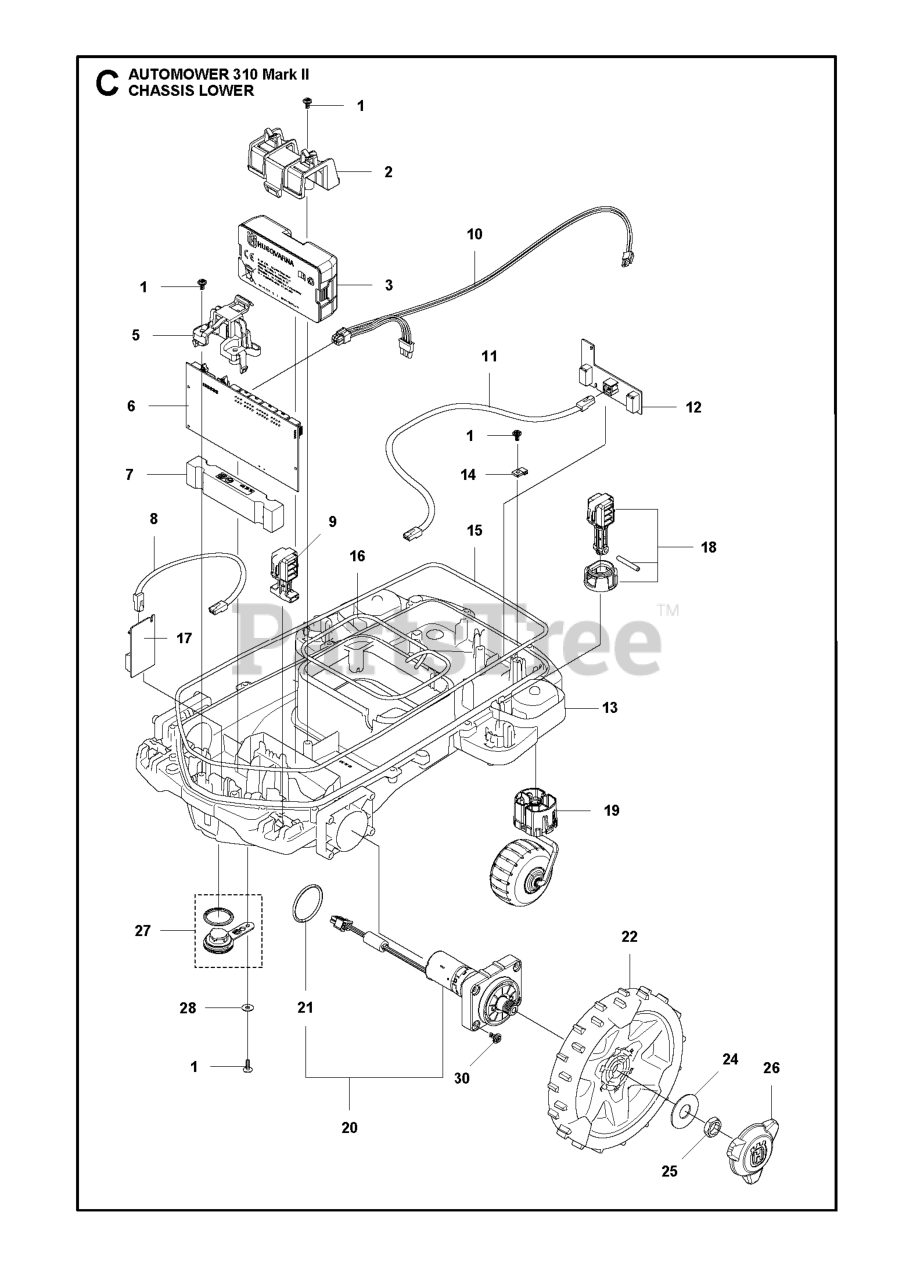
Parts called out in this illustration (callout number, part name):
1	SCREW ITXPANT
3	BATTERY:18V, 2.0AH, 36.0WH TYP
6	PRINTED CIRCUIT ASSY PCBA FOR
7	WEIGHT SQUARE BAR
9	STRUT TILT
14	CLAMP PCB
16	SEALING STRIP CUTTING SYSTEM
18	COLUMN ASSY P16
19	WHEEL ASSY SPINDLE INSIDE 2K
21	O-RING LIGHT GREY
24	WASHER WASHER REAR WHEEL 16X40
25	HEXAGON THIN NUT
26	HUB CAP REAR WHEEL NO CENTER P
30	SCREW ITXPANT
